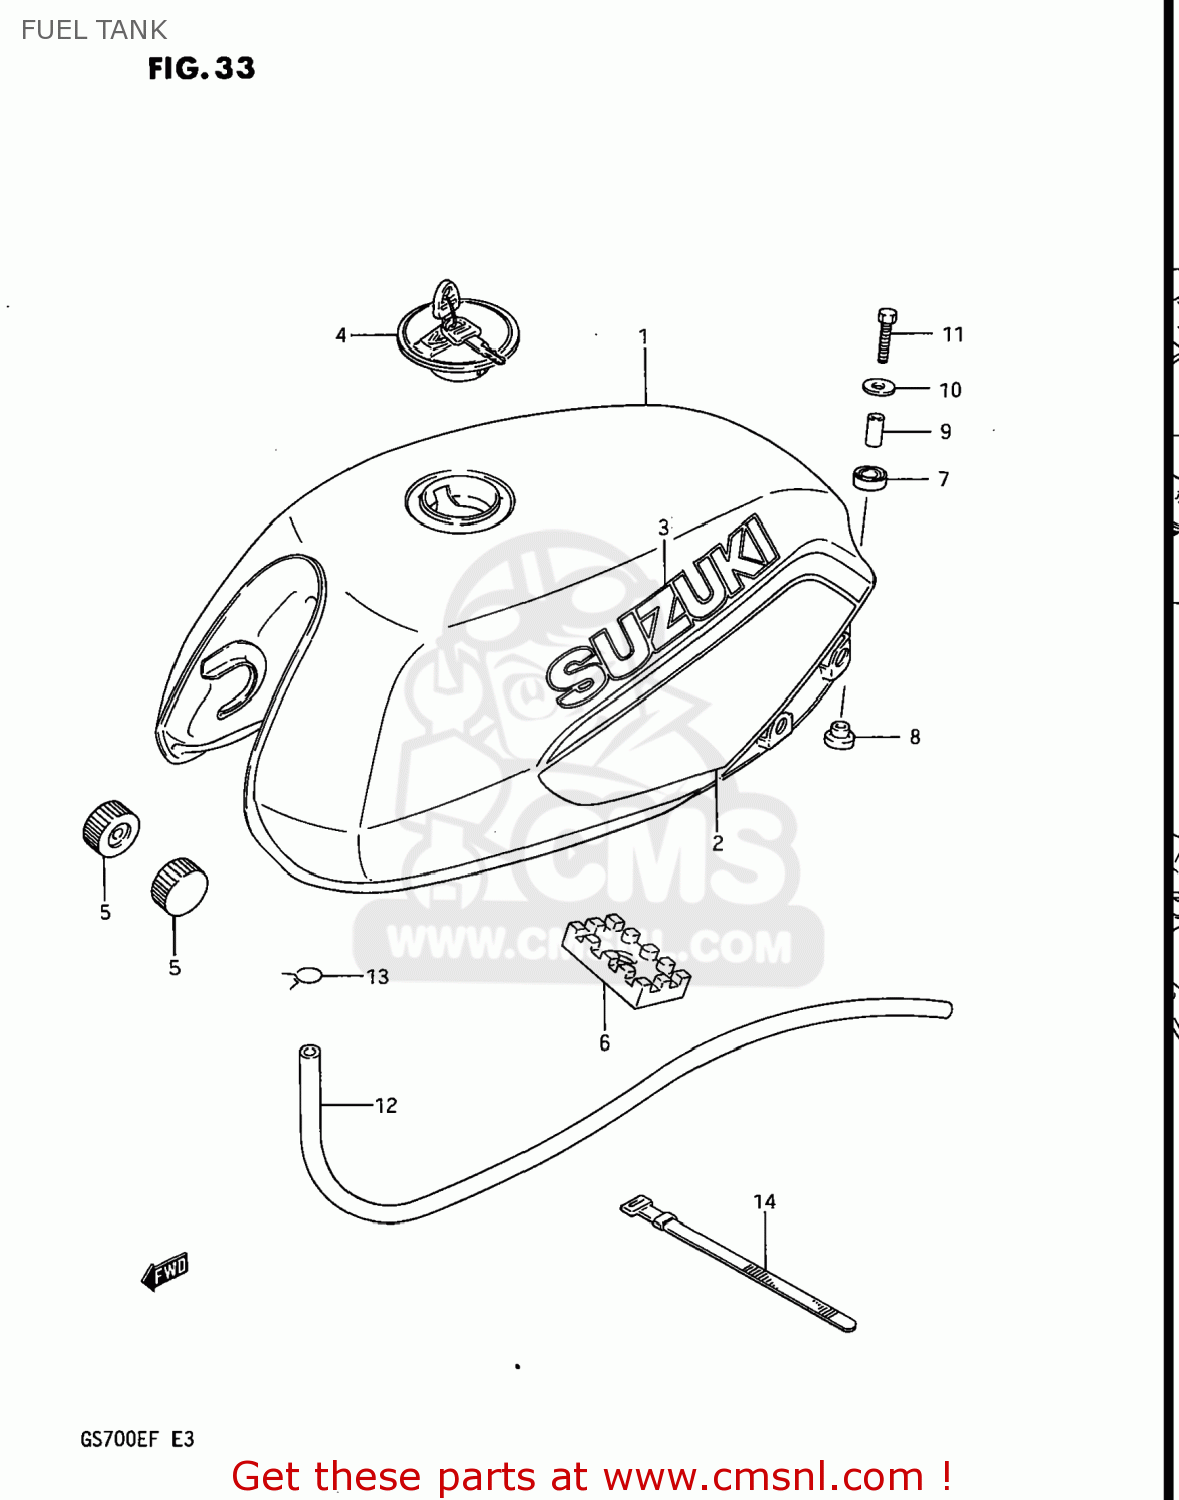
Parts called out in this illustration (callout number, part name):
1	TANK ASSEMBLY,FUEL
2	TAPE SET,FUEL TANK
3	EMBLEM
4	CAP SET,FUEL TANK
5	CUSHION
6	CUSHION,FUEL TANK CTR
7	CUSHION
8	CUSHION
9	SPACER
10	WASHER (6.5X24X1.6)
11	BOLT
12	HOSE,FUEL
13	CLIP
14	CLIP(ID:16)
